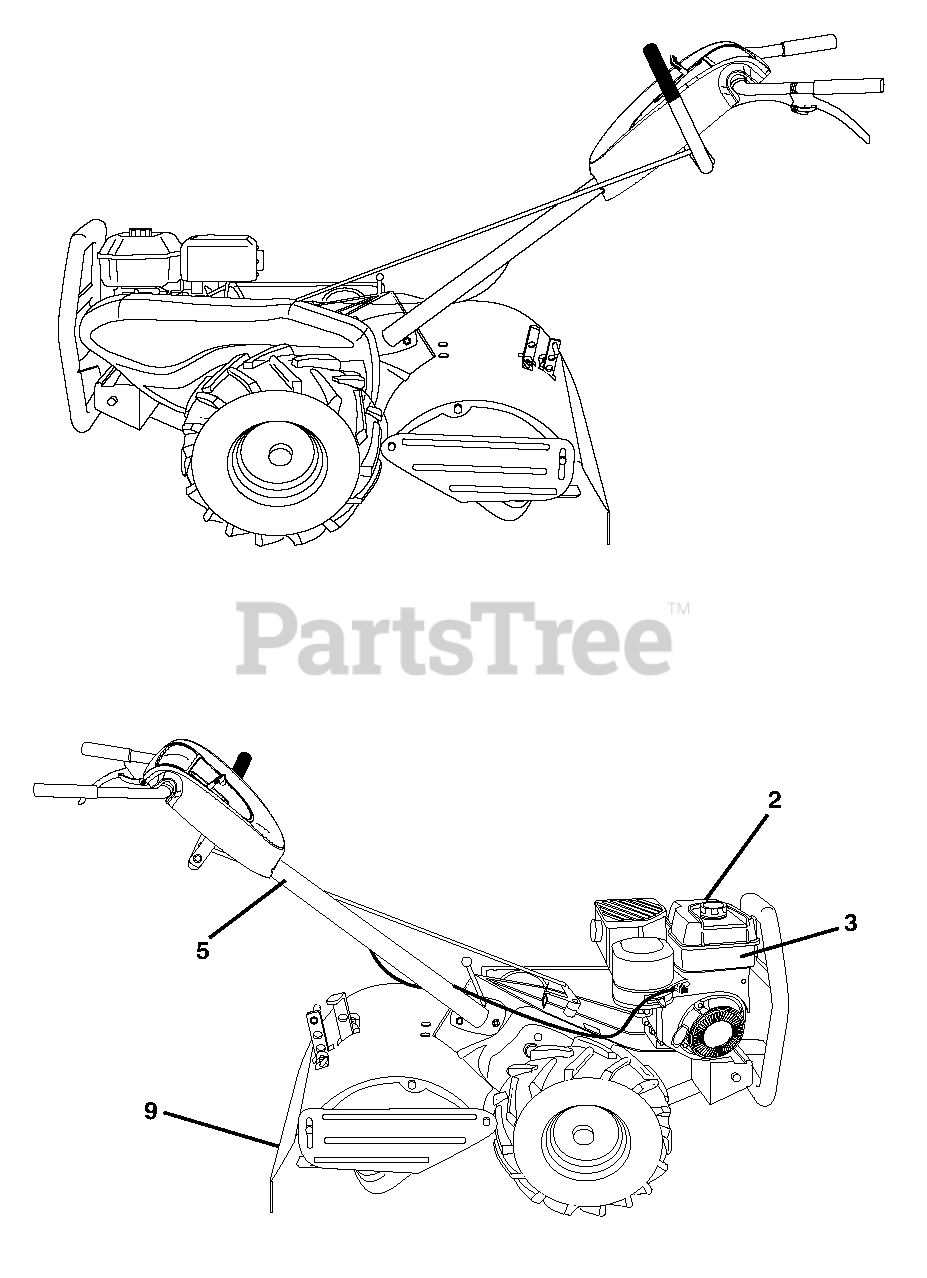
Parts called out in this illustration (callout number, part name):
2	DECAL.ETHANOL.E85 WARNING SYMB
3	DECAL, WARNING SPARK ARRESTOR
9	DECAL.DRT.WARN.ENG/F
